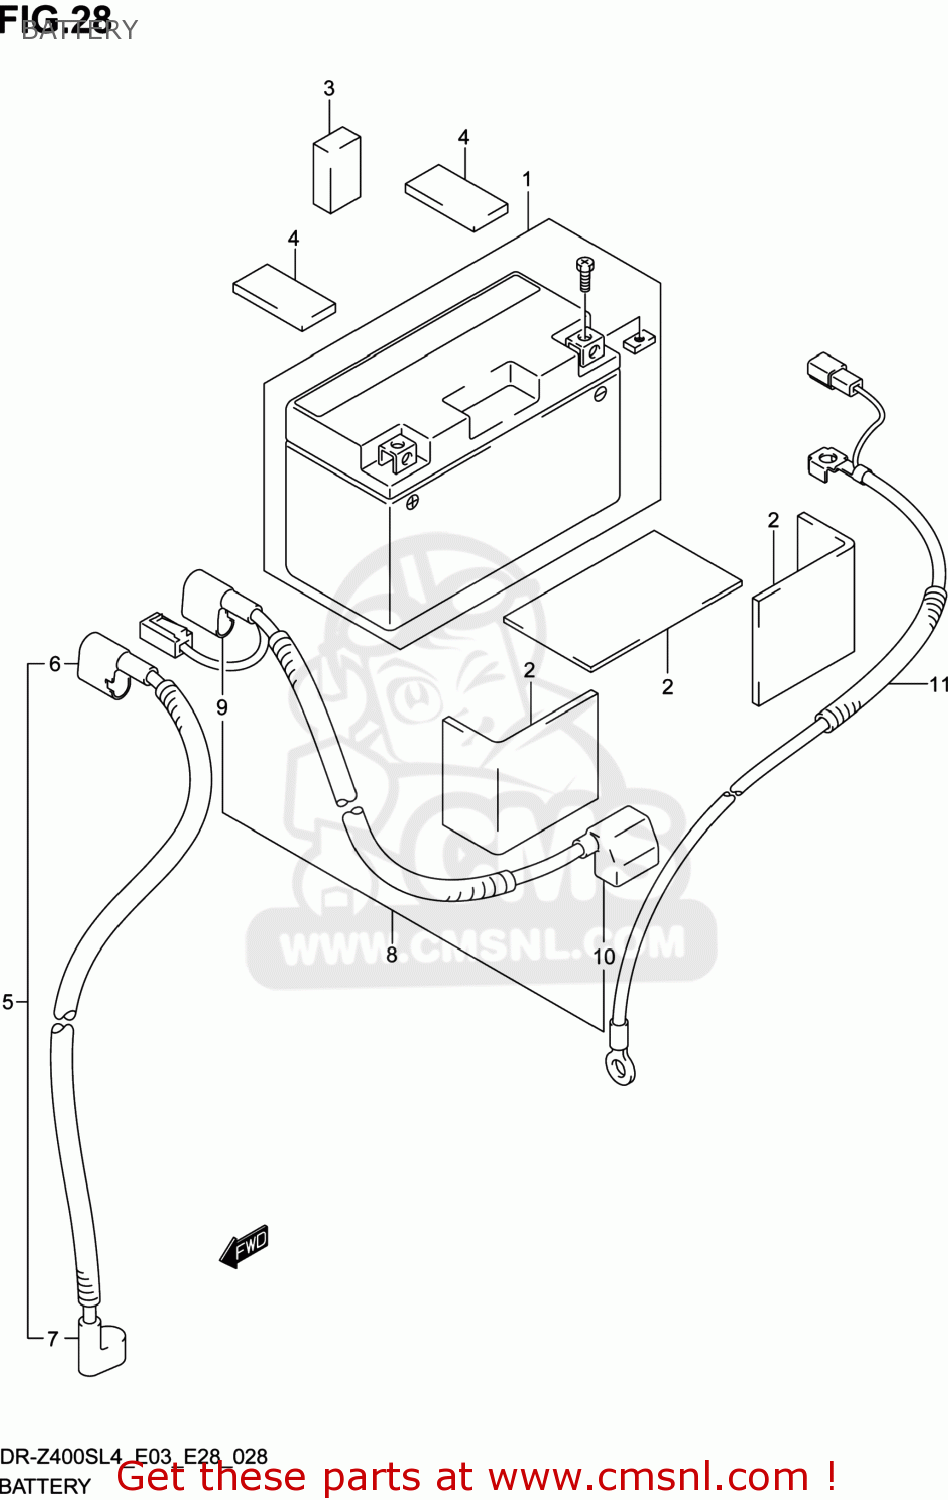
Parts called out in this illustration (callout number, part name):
1	BATTERY ASSY(YT7B-BS,12V6AH)
2	PROTECTOR(170X95X3.0)
3	PROTECTOR,BATTERY(70X100X6)
4	CUSHION(50X42X2.0)
5	WIRE,STARTER MOTOR LEAD
6	CAP,STARTER RELAY
7	CAP,STARTER MOTOR
8	WIRE,BATTERY PLUS LEAD
9	CAP,STARTER RELAY
10	CAP,BATTERY PLUS
11	WIRE,BATTERY MINUS LEAD
